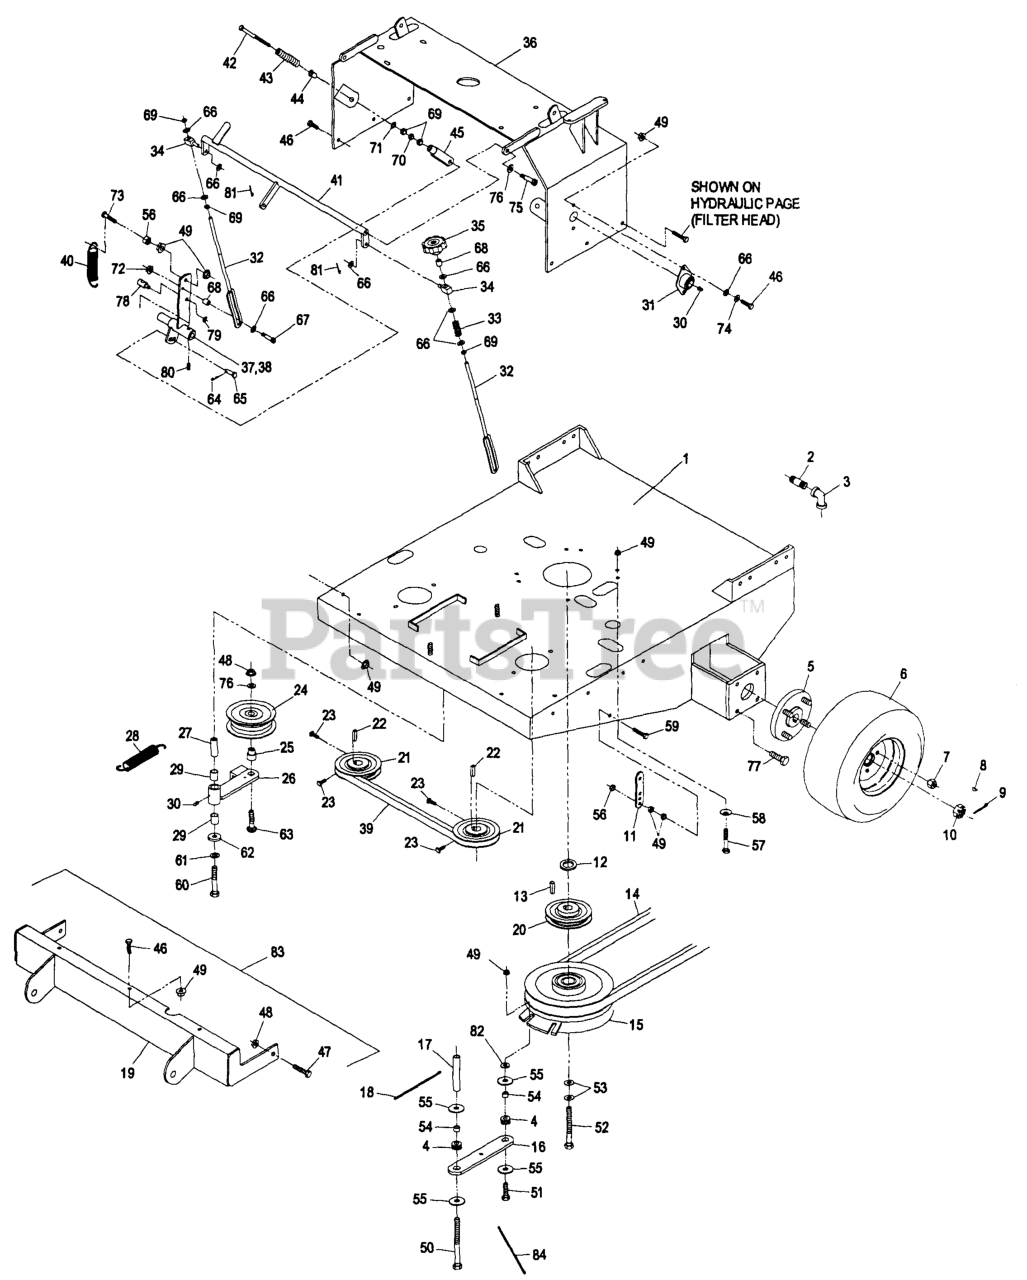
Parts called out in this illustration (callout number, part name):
1	Engine Deck Weldment
2	NIPPLE,PIPE
3	ELBOW-90 DEG
4	GROMMET
6	WHEEL AND TIRE ASM
8	KEY-WOODRUFF
9	PIN-COTTER
11	TAB-SPRING, EXTENSION
14	BELT,DECK DRIVE
15	KIT, CLUTCH ASSY
16	STRAP-CLUTCH, BRAKE
17	SPACER-SHIELD
18	TIE-CABLE
19	WLD,SULKY HITCH
20	PULLEY
21	SHEAVE ASM
23	SCREW-SET
25	BUSHING-IDLER
26	IDLER ARM ASM
27	BUSHING
28	SPRING-EXTENSION
29	SLEEVE-BEARING
31	BEARING-FLANGE, SIDE
32	LINK,SPEED CONTROL
33	SPRING-COMPRESSION
35	KNOB-TRACKING
40	SPRING-EXTENSION
41	WLD,CRANK SPEED CONTROL
42	BOLT-RETURN, NEUTRAL
43	SPRING-RETURN, NEUTRAL
44	BUSHING-FLANGED
45	YOKE-ADJUSTABLE
53	WASHER-SPRING
58	WASHER-SPRING
59	BOLT-TAP, HH
64	PIN-COTTER
65	PIN-CLEVIS
67	SCREW-HSH
74	WASHER-LOCK
75	SCREW-HSH
80	SCREW-SET
83	Hitch Kit, Sulky
84	TIE-PLASTIC
